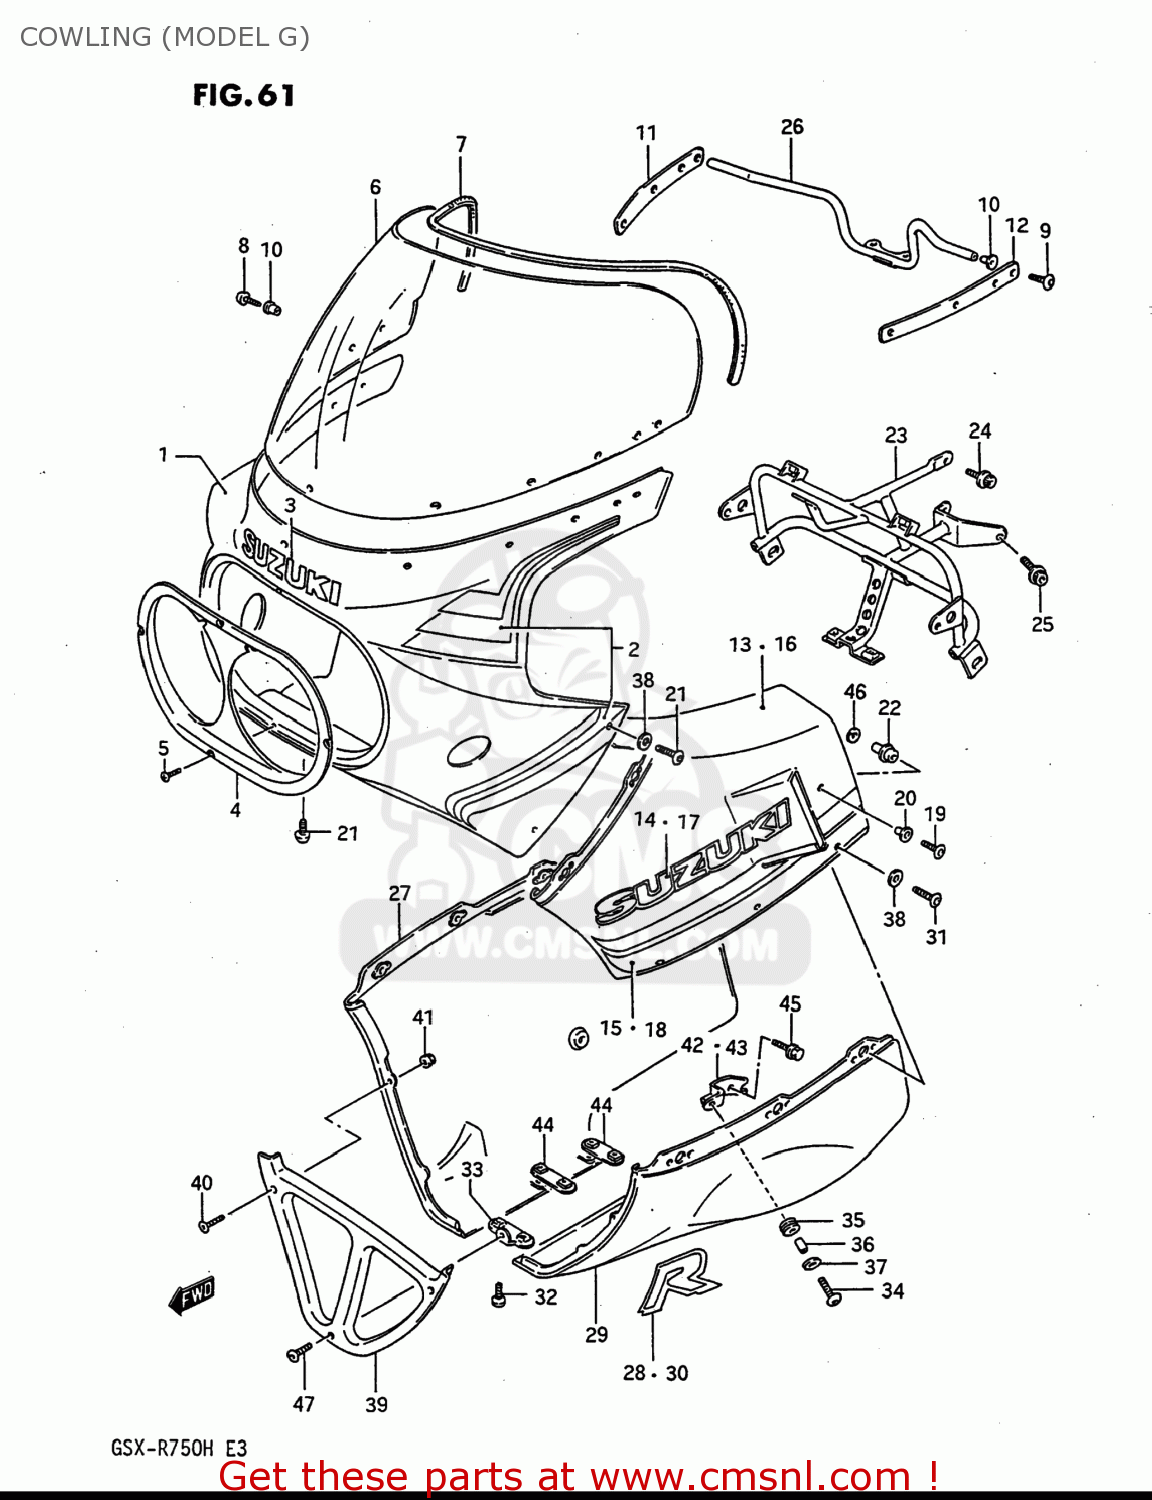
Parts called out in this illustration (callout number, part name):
1	COWLING SET
2	TAPE SET,COWLING
3	EMBLEM,LEG SHIELD
4	COVER,COWLING FR
5	SCREW
6	WINDSCREEN
7	MOLDING,SCREEN
8	SCREW(5X14)
9	SCREW(5X18)
10	NUT,COWLING SCREEN
11	PLATE,RR VIEW MIRROR,R
12	PLATE,RR VIEW MIRROR,L
13	COVER ASSEMBLY,COWLING
14	EMBLEM
15	TAPE SET,COWL SIDE RH
16	COVER,COWLING SIDE,LEFT
17	EMBLEM
18	TAPE SET,COWL SIDE LH
19	SCREW(6X12)
20	WASHER
21	SCREW(6X16)
22	CUSHION,COWLING
23	BRACE,COWLING
24	BOLT
25	BOLT
26	BRACE,COWLING BODY RR
27	COVER,COWLING,LOWER,RIGHT
28	EMBLEM
29	COVER,COWLING,LOWER,LEFT
30	EMBLEM
31	SCREW(6X16)
32	SCREW(6X16)
33	BRACE,COWLING LWR COVER
34	SCREW(6X20)
35	CUSHION
36	SPACER
37	WASHER(6.5X18X1)
38	WASHER(6.5X15X1.0)
39	COVER,COWLING,LOWER,FRONT
40	SCREW(5X14)
41	NUT
42	BRACE,COWLING LWR,R
43	BRACE,COWLING LWR,L
44	BRACE,COWLING LWR COVER RR
45	BOLT
46	WASHER
47	SCREW(6X16)
